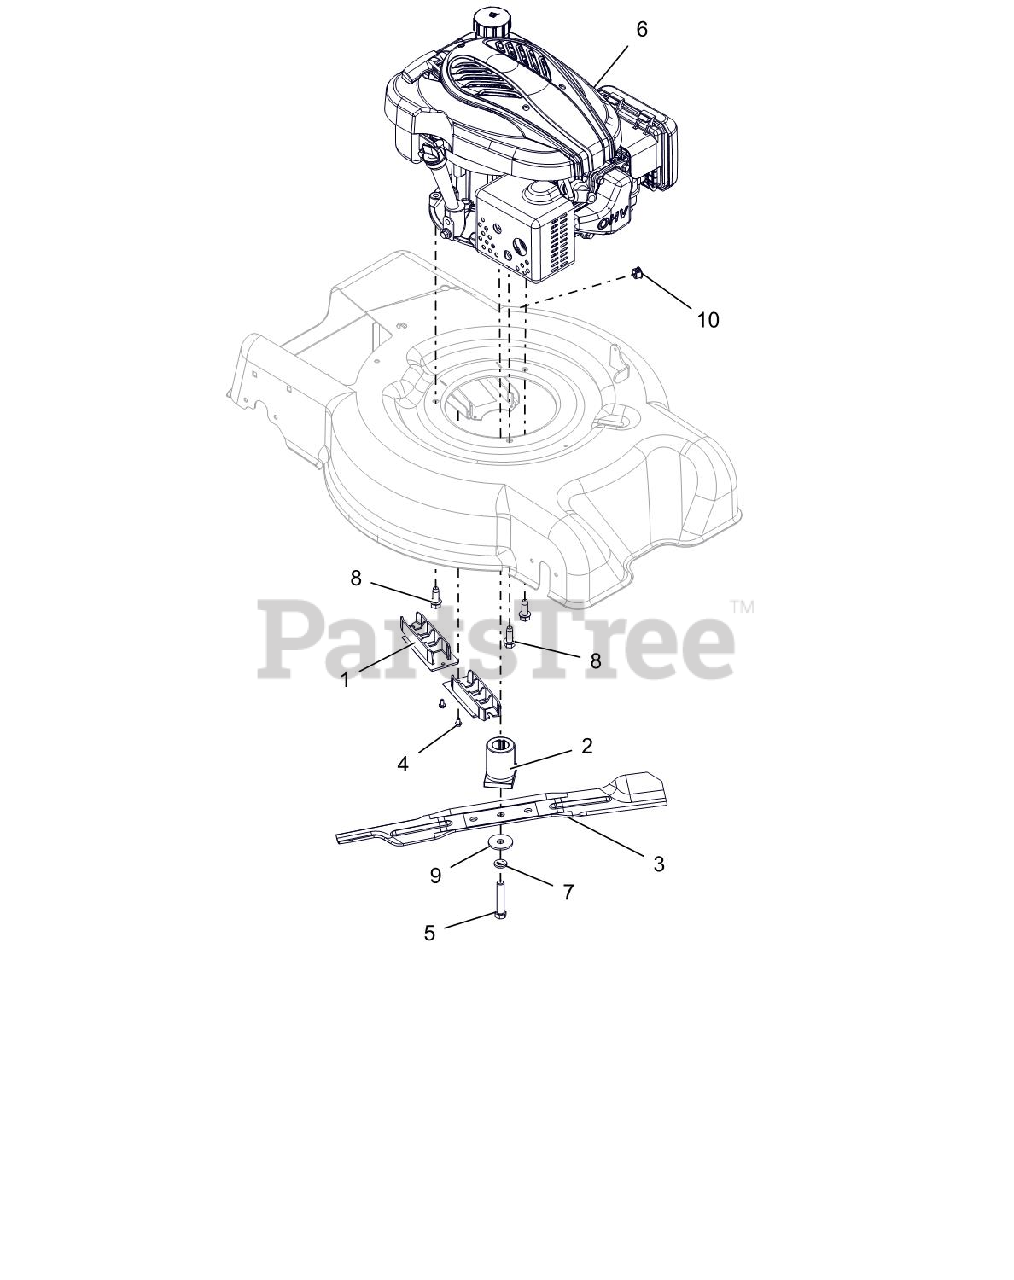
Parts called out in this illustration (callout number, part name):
1	GUIDE, BELT INNER
2	ADAPTER, BLADE
3	BLADE, MOWER 21" HIGH LIFT
4	SCR-TAP 10-24X.375 PRE-COAT 80
5	@BLT-HEX .4375-20X2.25 GR8 YWZ
6	ENGINE, LONCIN 159CC VERT.
7	@WSHR-LK .44X.109 REG YWZC
8	@SCR-TAP .38-16X1.00 HWH TR YZ
9	WSHR-FL-STL .4375X1.50X.125 YZ
10	PLUG, DOME-BLACK, .625 DIA
